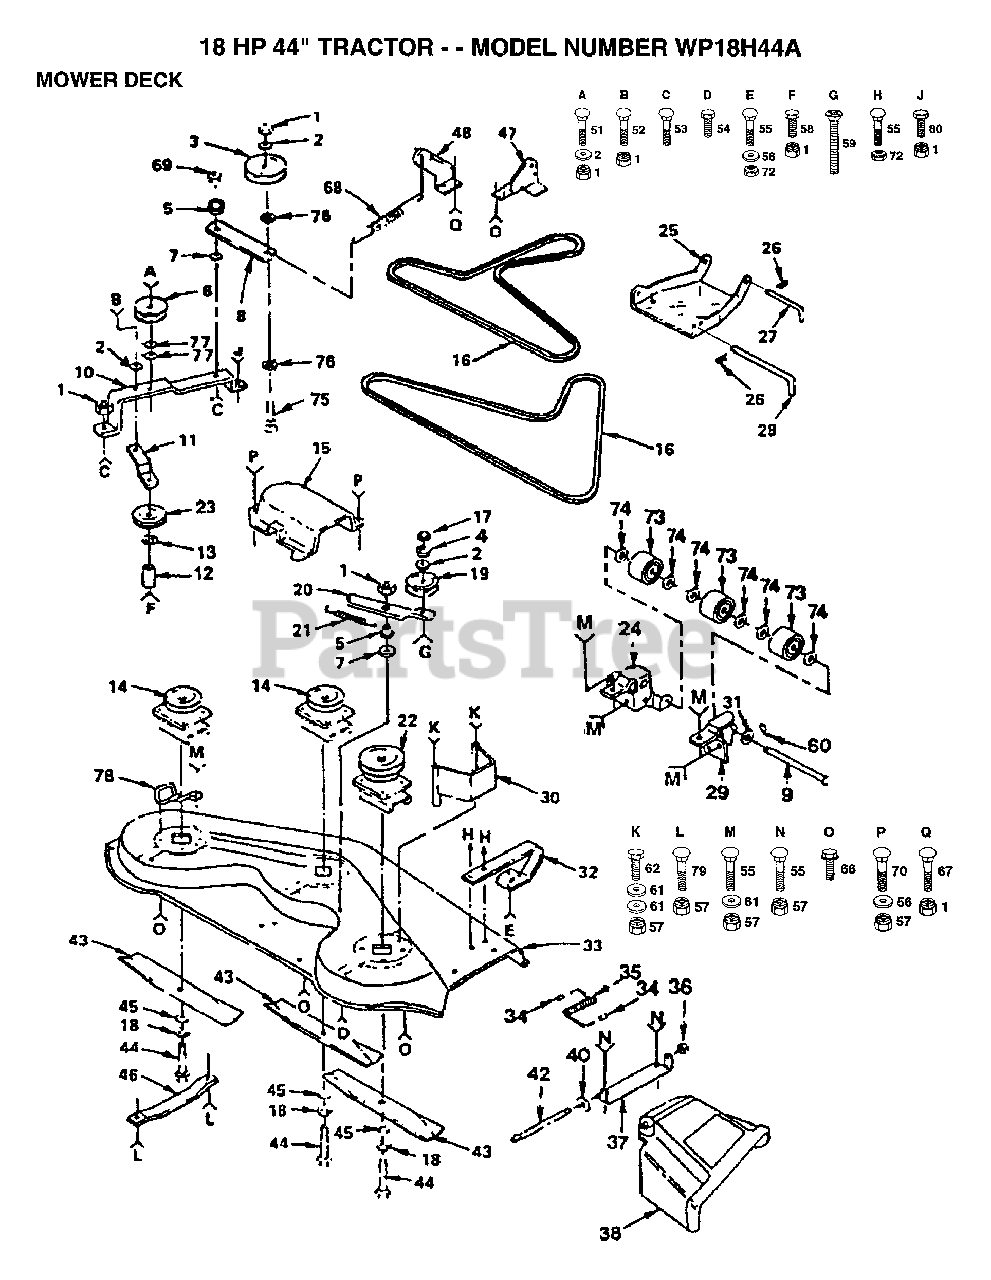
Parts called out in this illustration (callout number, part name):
2	WASHER
3	PULLEY IDLER
4	LOCKWASHER
5	SPACER RETAINER
6	IDLER-INSIDE T
7	"WASHER, WEAR LT"
8	ARM IDLER
9	PIVOT PIN T
10	"SUPPORT YT, BAR"
11	BRACE-IDLER YT
12	SPACER
13	WASHER
15	GUARD YT
16	BELT-V.79.1.MWR
17	NUT.HEX.3/8-16UNC
19	IDLER.FLAT.GTV
20	ARM-IDLER YT
22	JACKSHAFT
23	IDLER-FLAT T
24	BRACKET LH YTH
25	LINK.PARALLEL
26	SPRING.RETAINER
27	"ROD, FRT. PARAL T"
28	HINGE PIN T
29	BRACKET RH YTH
30	GUARD BELT HYT
34	CAP-SLEEVE LT
36	NUT PUSH M
38	DEFLECTOR SHIELD
40	WASHER
42	ROD-HINGE T
44	BOLT.3/8-24X1-1/2
45	WASHER
46	RUNNER-LH M
47	BRKT SUSP REAR RH
48	BRKT SUSP REAR LH
51	BOLT
53	BOLT
55	BOLT
56	WASHER
58	BOLT - HEX 3/8 - 16 X 3
59	SCREW YT
60	COTTER PIN
61	WASHER M
62	BOLT
66	SCREW
67	BOLT
68	"SPRING.EXT.8.5"""
69	LOCKNUT
73	ROLLER T
74	WASHER T
75	BOLT
76	WASHER
77	WASHER
78	BELT RETIANER
79	BOLT
80	BOLT
